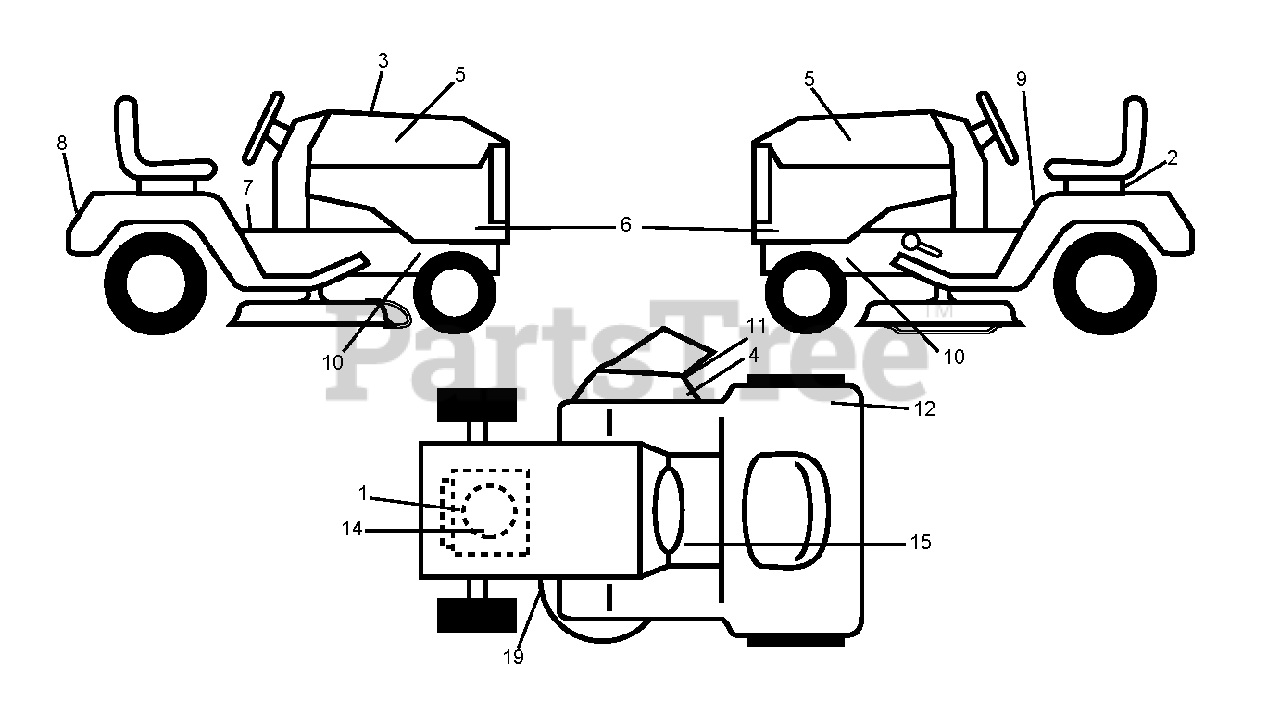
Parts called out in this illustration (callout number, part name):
2	DECAL BTRY SYMBOLS
4	DECAL, DEFLECT WARNING
7	DECAL PARK BRAKE
11	DECAL.INTERNATIONL.CUTFINGER
19	DECAL.V-BELT.SCHEMATIC.36/38/9
